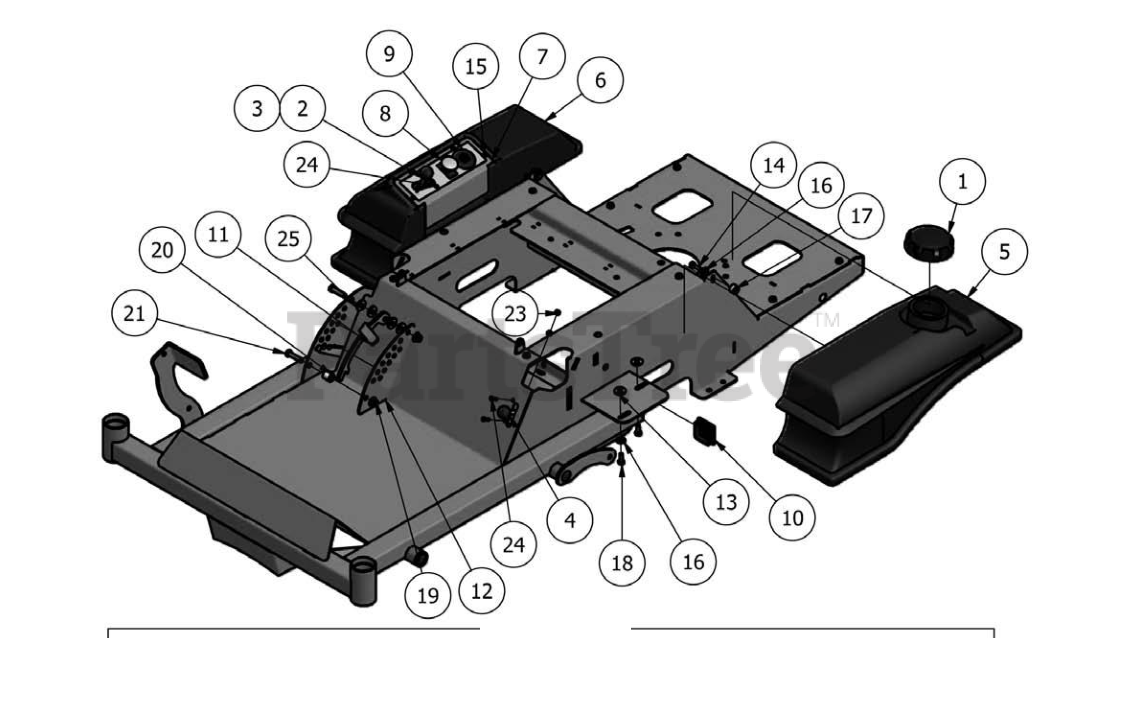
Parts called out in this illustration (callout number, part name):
2	Throttle Lever W/Choke For Kawasaki
3	Throttle Lever W/Choke for Briggs
4	Brake Lever
5	3 Gallon Fuel Tank
6	Fender Console
7	MZ Control Panel
8	PTO Engager
9	Ignition Switch
10	Ignition Key
11	2x2 Square Plug
12	Deck Level Lock
13	MZ Height Indicator Plate
14	.360ID Plastic Washer
15	5/16-18 x 1 Grade 5 Hex bolt Zinc
16	10-32 x 3/8 Button Socket C/S 18-8 SS
17	5/16 Lock Washer Zinc
18	MZ Tank Spacer
19	5/16-18 x 3/4 Grade 5 Hex bolt Zinc
20	3/8 Nylock Flange Nut
21	3/40D x 1/2ID x 3/4 Spacer
22	3/8-16 x 1-1/2 GR5 Hex Bolt
23	10-24 Nylon Insert Locknut Zinc Orange Nylon
24	10-24 x 5/8 Button Socket C/S 18-8 SS
25	.39 Plastic Washer
